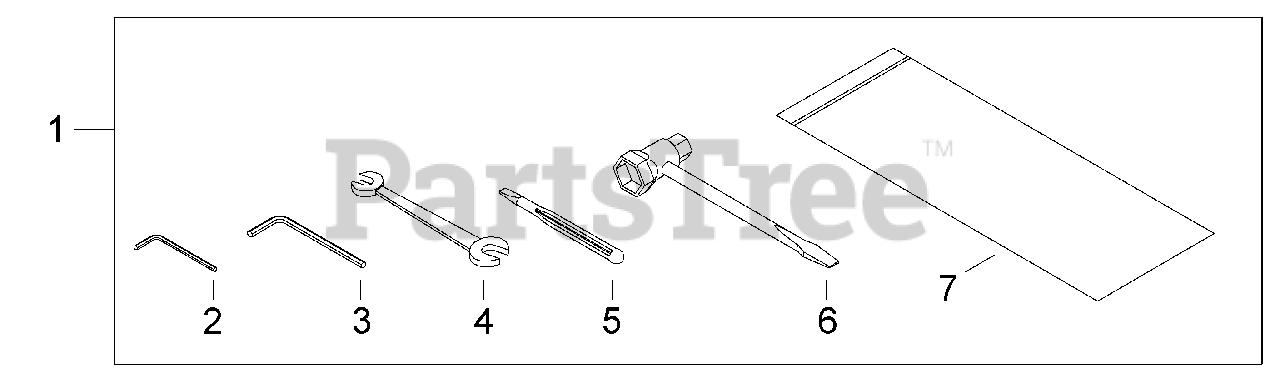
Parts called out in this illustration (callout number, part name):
1	TOOL KIT, SERVICE
2	WRENCH, ALLEN 3 MM
3	WRENCH, ALLEN 4 MM
4	SPANNER 8×10
5	SCREWDRIVER, PLASTIC
6	T-WRENCH 13×19 MM
7	BAG, TOOL
